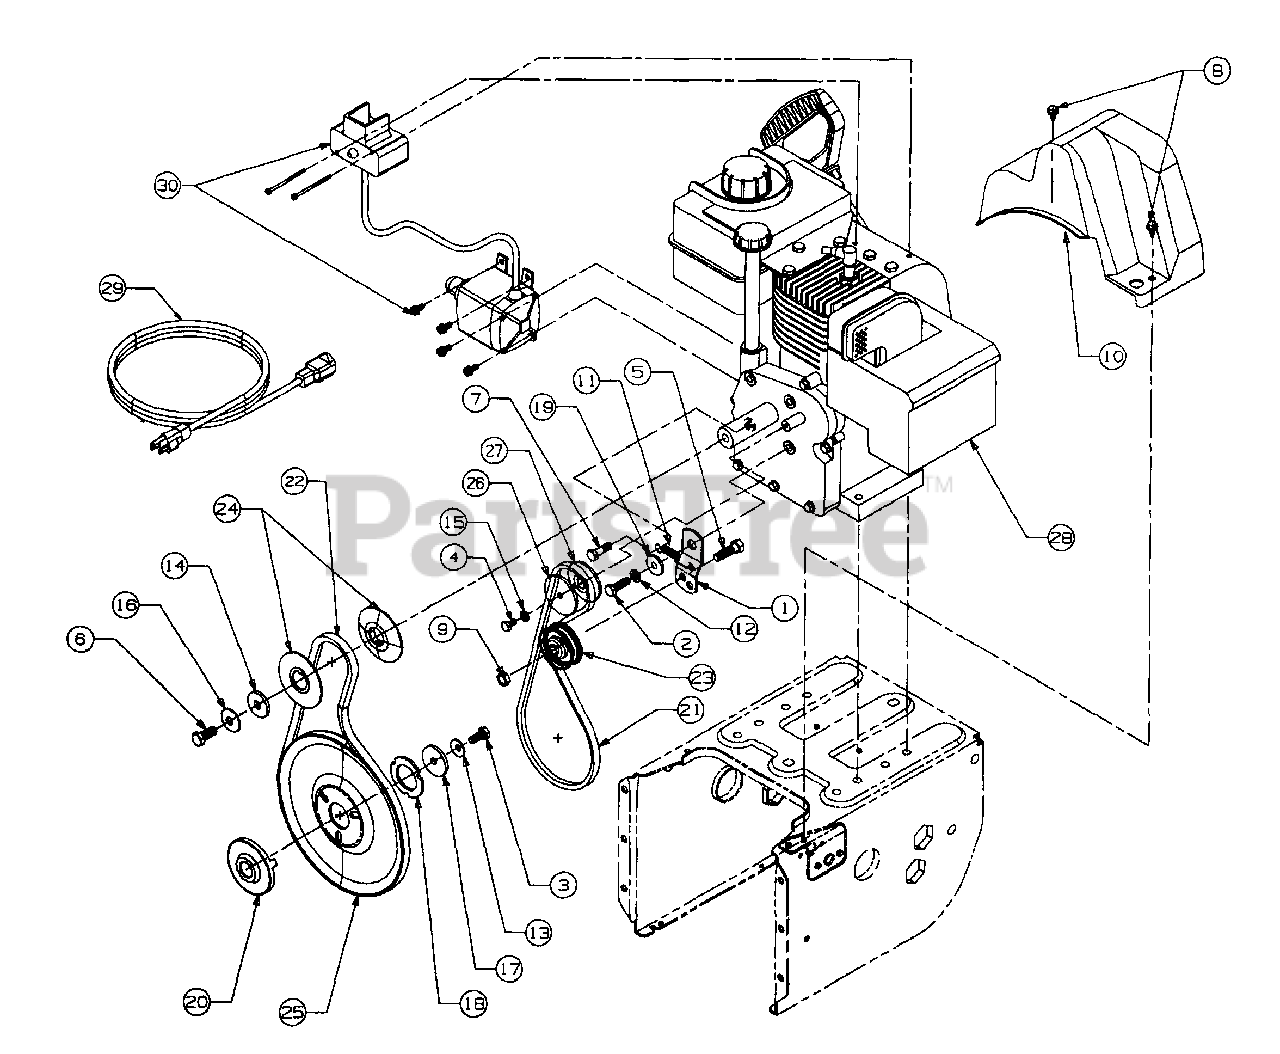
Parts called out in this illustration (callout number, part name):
3	Lock Hex Cap Screw, 5/16-24
4	Hex Cap Screw, 1/4-28 x .5
5	Hex Cap Screw, 3/8-16 x 1.25
6	Hex Cap Screw, 3/8-24
7	Hex Screw, 5/16-24 x .75
8	Screw
9	Hex Jam Nut
10	Belt Cover
11	Spring
12	Washer
13	Bell Washer
14	Washer
15	Washer
16	Bell Washer
17	Flat Washer
18	Washer
19	Spacer
20	Adapter Pulley
21	V-Belt
22	V-Belt Matched
23	Flat Idler
24	Half Pulley
25	Auger Pulley
26	Half Pulley
27	Half Pulley
28	Engine
29	Extension Cord
30	Electric Start Kit
